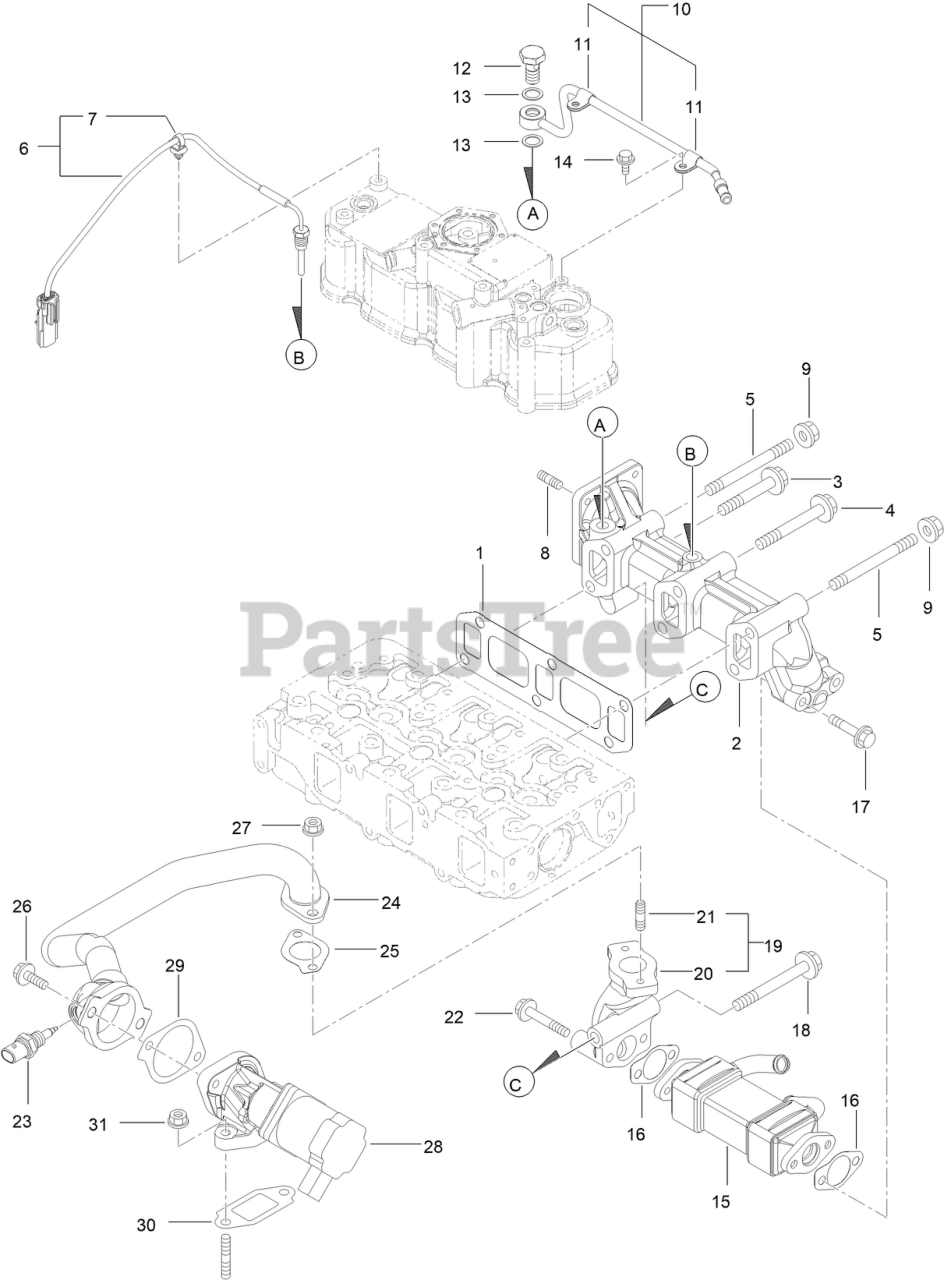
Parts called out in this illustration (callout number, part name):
1	GASKET-MANIFOLD, EXHAUST
2	MANIFOLD-EXHAUST
3	BOLT-FLANGE
4	BOLT-M10
6	SENSOR-TEMP, EXHAUST
7	BAND-CLIP
10	EXHAUST PIPE ASM
12	BOLT-JOINT, PIPE
13	GASKET
15	COOLER-E G R
16	GASKET-COOLER, E G R
18	BOLT-FLANGE
19	E G R PIPE ASM
20	PIPE-OUT, E G R
23	SENSOR-GAS TEMP, E G R
24	E G R PIPE ASM
25	GASKET
28	VALVE-E G R
29	GASKET-INTAKE VALVE, E G R
30	GASKET-OUT VALVE, E G R
